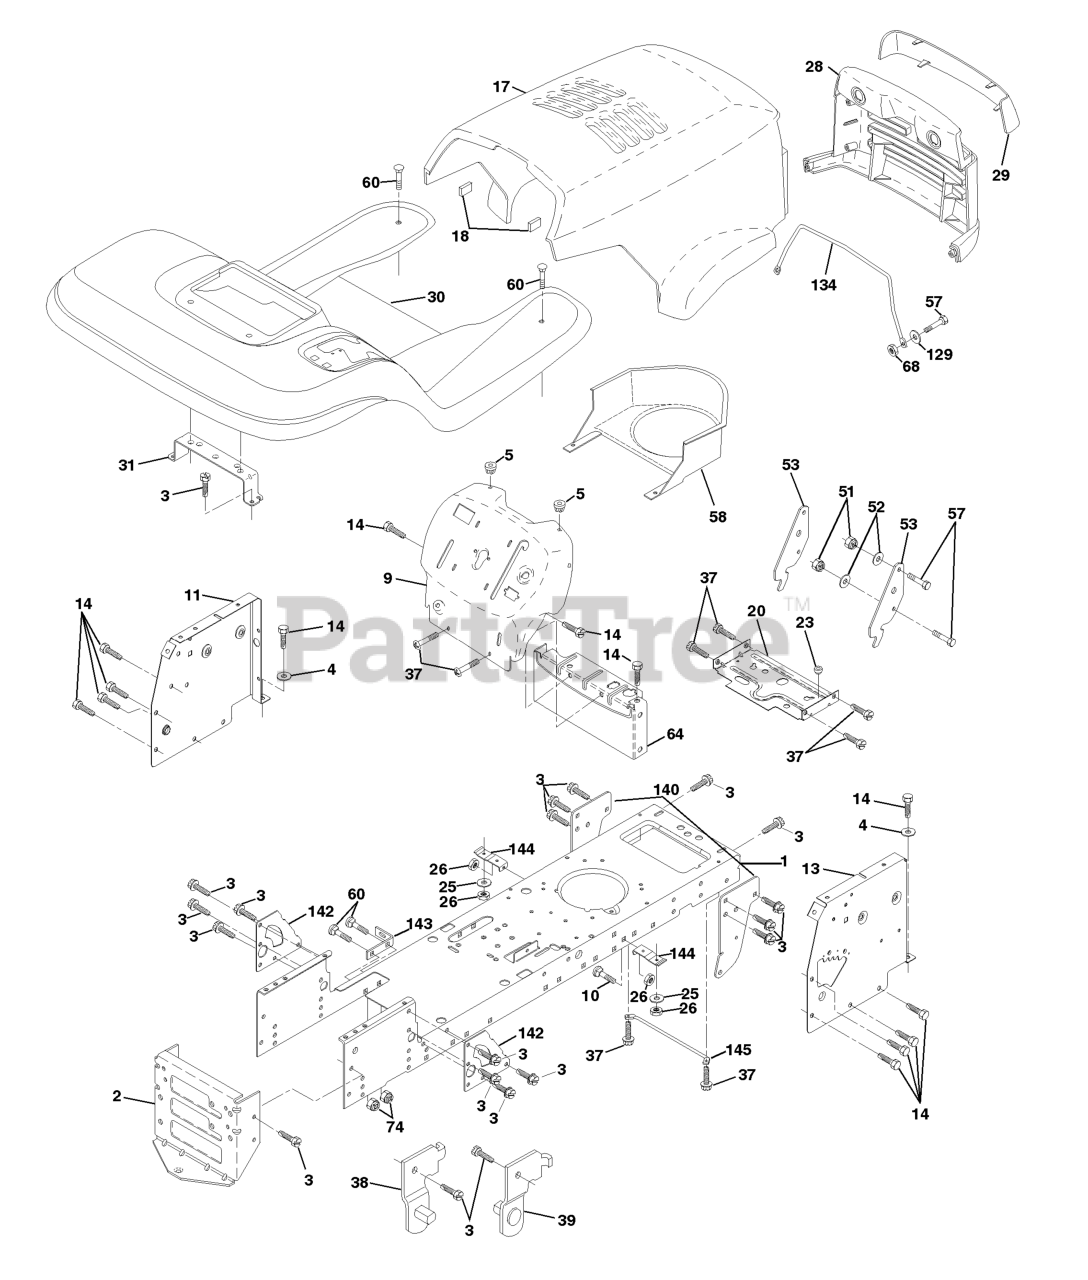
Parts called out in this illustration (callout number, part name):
2	STRETCH DRAWBAR
3	SCREW
4	Washer 13/32 x 3/4 x 16 Ga.
5	BUMPER.RUBBER.HOOD
9	DASH PANEL
10	BOLT D
11	PANEL DASH LH
13	PANEL DASH RH
14	SCREW LT
17	HOOD
18	BUMPER HOOD T
20	PLATE MTG
23	BUSHING.SNAP.NYL.BLK.
25	WASHER
26	NUT
28	GRILL
29	LENS
30	FENDER FOOTREST
31	BRACKET.SUPPORT.FENDER
37	Screw Thdrol 6/16-18 x 1/2 TYT
38	BRACKET LH PIVOT
39	BRACKET RH PIVOT
51	LOCKNUT.NYLOC.1/4-20
52	WASHER
53	BRACKET PNT PICK OFF LT/PL
57	BOLT
58	AIR DUCT P/L/LT
60	Bolt Rdhd Sqnk 3/8-16unc x 3/4
64	DASH LOWER
68	NUT
129	WASHER
134	ROD SUPPORT HOOD LT/PL HUS.
140	BRACKET SUSPENSION FRONT
142	PLATE REINFORCEMENT
143	BRACKET, SWAY BAR
144	BRACKET FOOTREST
145	ROD PIVOT CHASSIS/HOOD
